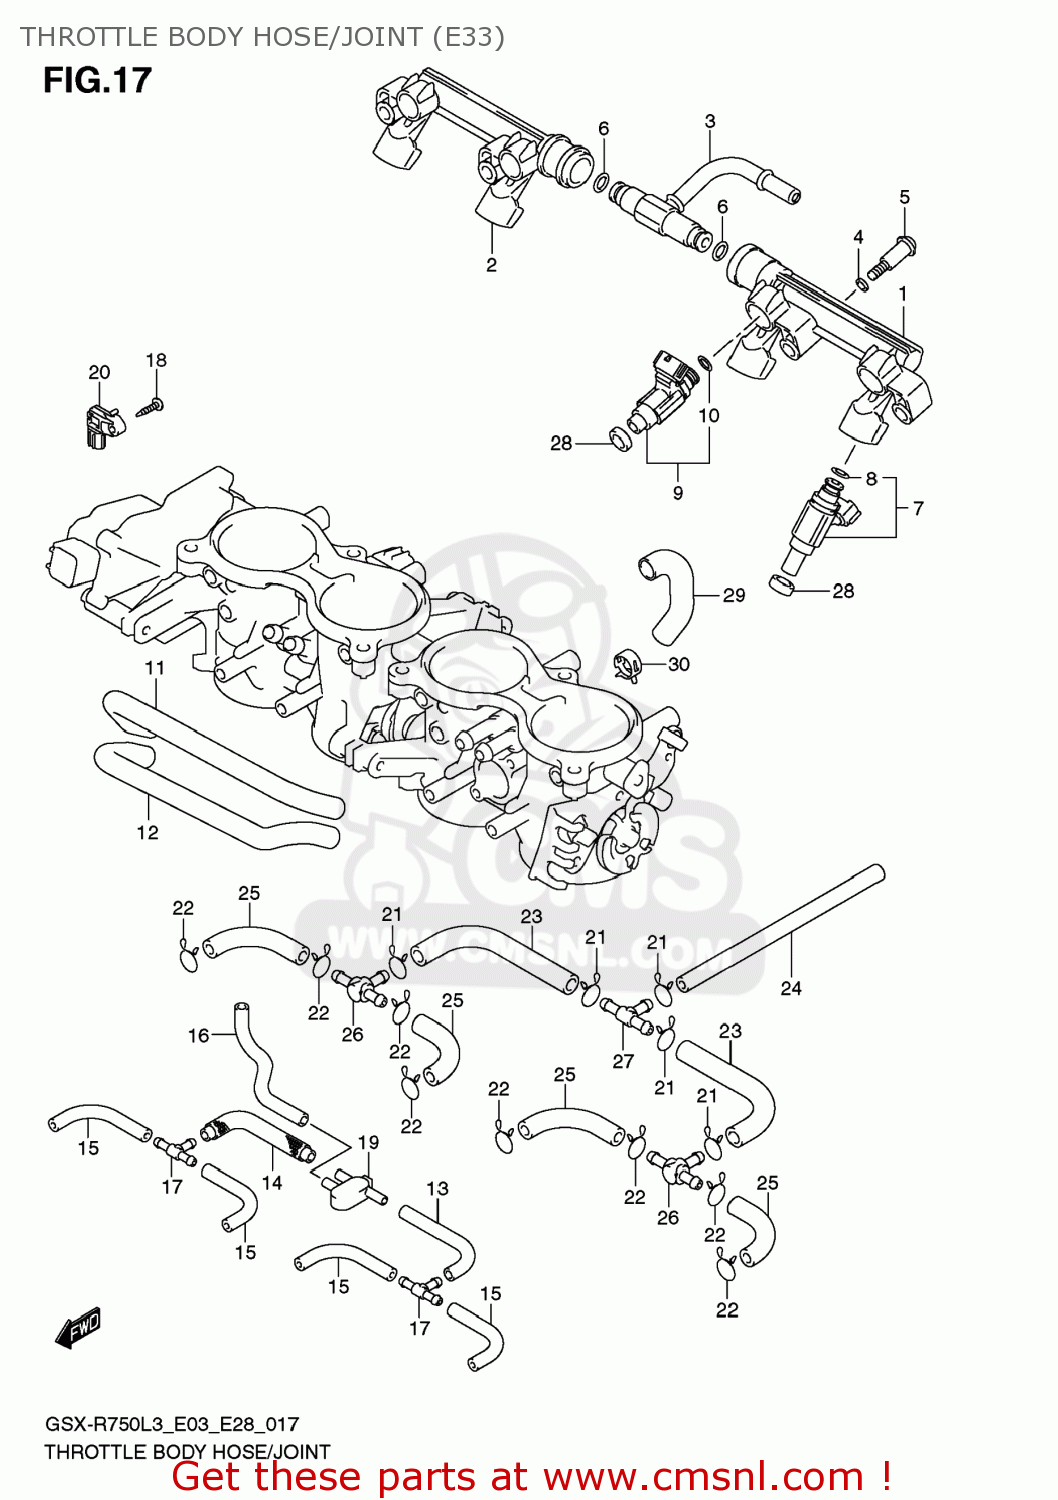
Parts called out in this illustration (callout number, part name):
1	DELIVERY PIPE
2	DELIVERY PIPE
3	NIPPLE ASSY
4	PACKING (NAS)
5	SCREW
6	O RING
7	INJECTOR ASSY
8	O-RING
9	INJECTOR ASSY
10	O-RING
11	HOSE
12	HOSE
13	HOSE
14	HOSE
15	HOSE
16	HOSE
17	3WAY,VACUUM HOSE
18	SCREW
19	JOINT
20	SENSOR,BOOST
21	CLIP
22	CLIP
23	HOSE
24	HOSE
25	HOSE
26	NIPPLE
27	NIPPLE
28	SEAL
29	HOSE
30	CLIP
